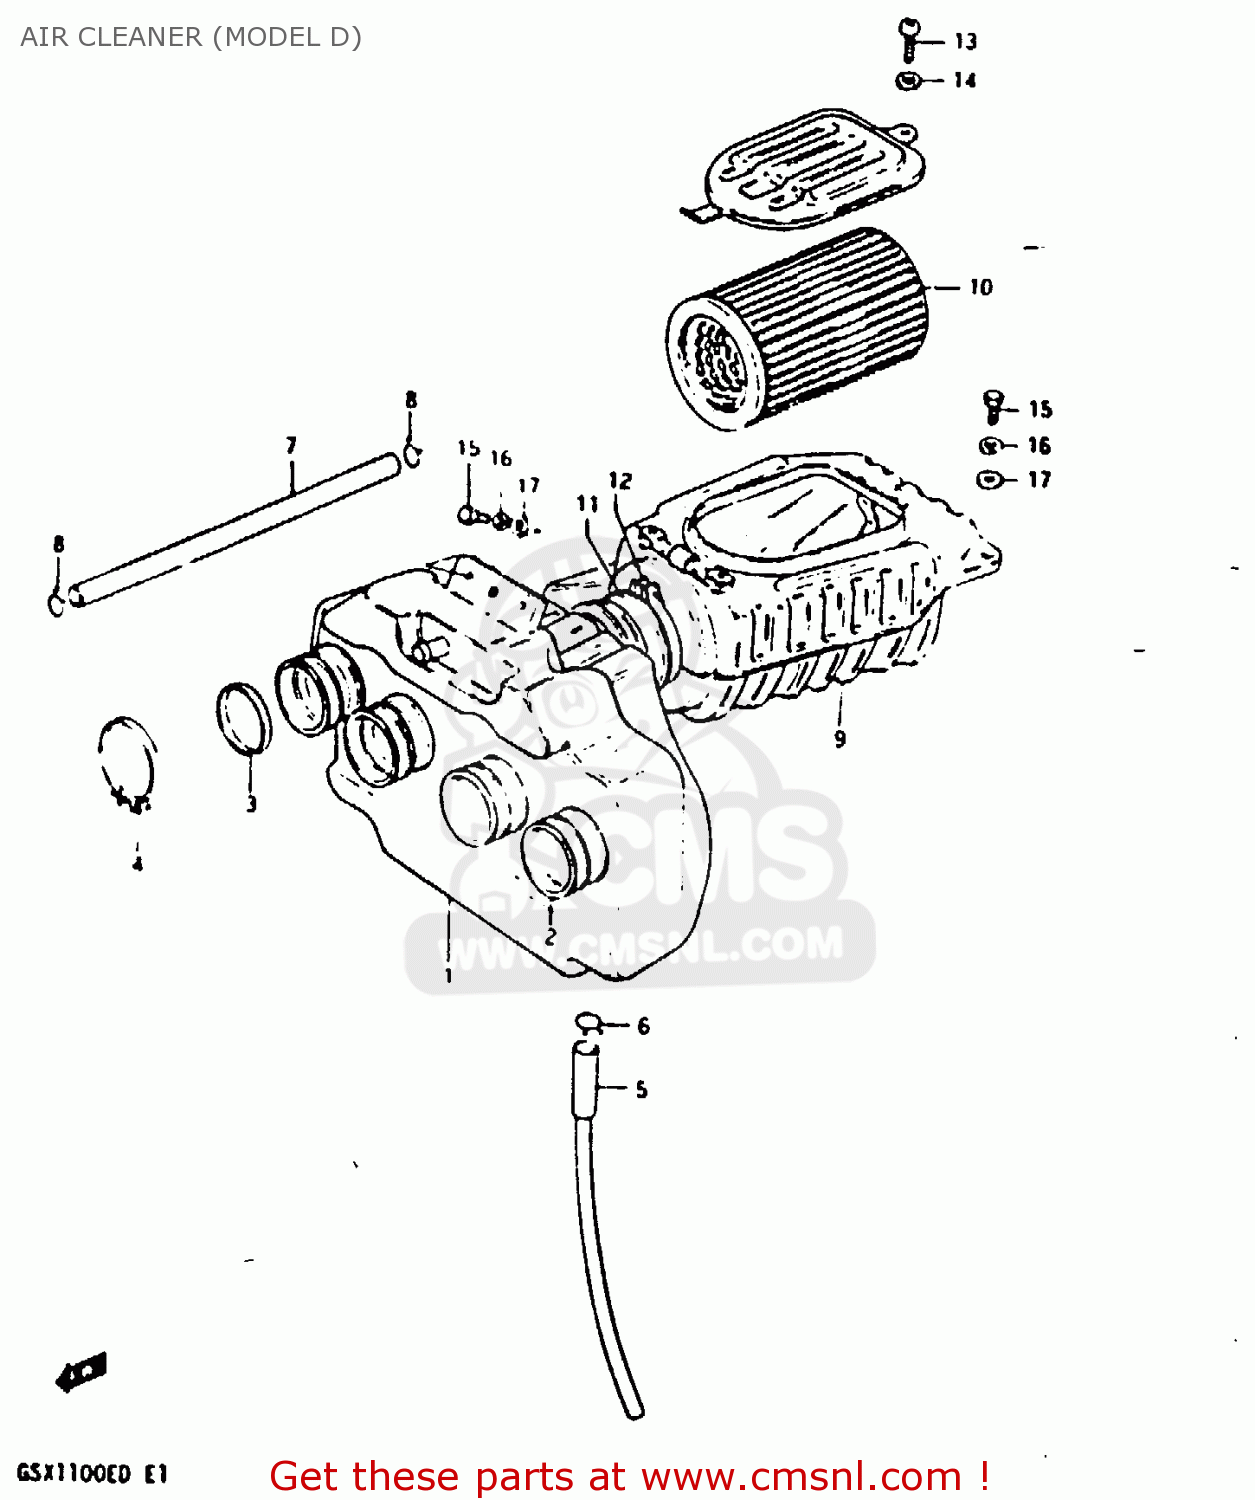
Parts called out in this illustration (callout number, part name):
1	CASE,AIR CHAMBER
2	TUBE,AIR CLEANER OUTLET
3	RING,CARBURETOR AIR INLET HOSE
4	CLAMP
5	DRAIN TUBE
6	CLIP
7	HOSE
8	CLIP
9	CASE SET, REAR
10	FILTER ASSY
11	HOSE,AIR CLEANER
12	BAND
13	SCREW
14	WASHER
15	BOLT
16	LOCK WASHER
17	WASHER
